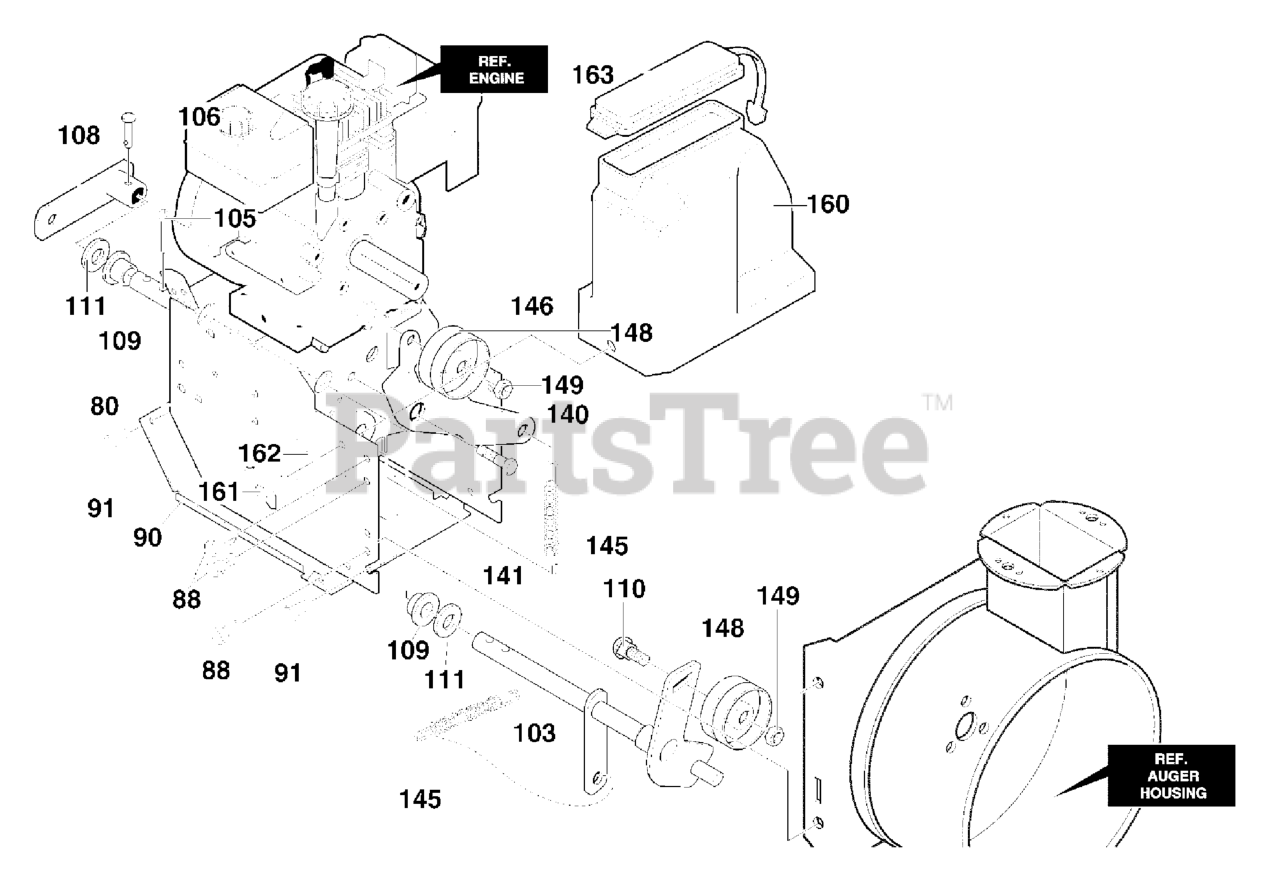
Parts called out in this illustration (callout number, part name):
80	FRAME ASSY
88	SCREW, 5/16-18 x 0.50
90	COVER, BOTTOM
91	SCREW, 1/4-20X .63
103	IDLER ASSEMBLY
105	PIN, HAIR .38DIAX1.64LG
106	PIN, KLIK 3/16" DIA
108	ASSY., SPRING ATTACH
109	BEARING, FL.
110	BOLT, 3/8-16X1.25 CARR.
111	WASHER, FLAT
140	LEVER, IDLER ARM TRACTION
141	BOLT, .625X.135 HHSH 5/16-18
145	IDLER SPRING TRACTION DRIVE
146	SCREW, 3/8-16 x 1.25
148	PULLEY, IDLER
149	NUT, 3/8-16
160	COVER, BELT
161	SCREW, 1/4-20X .63
162	WASHER, FLAT
163	LID, BELT COVER
